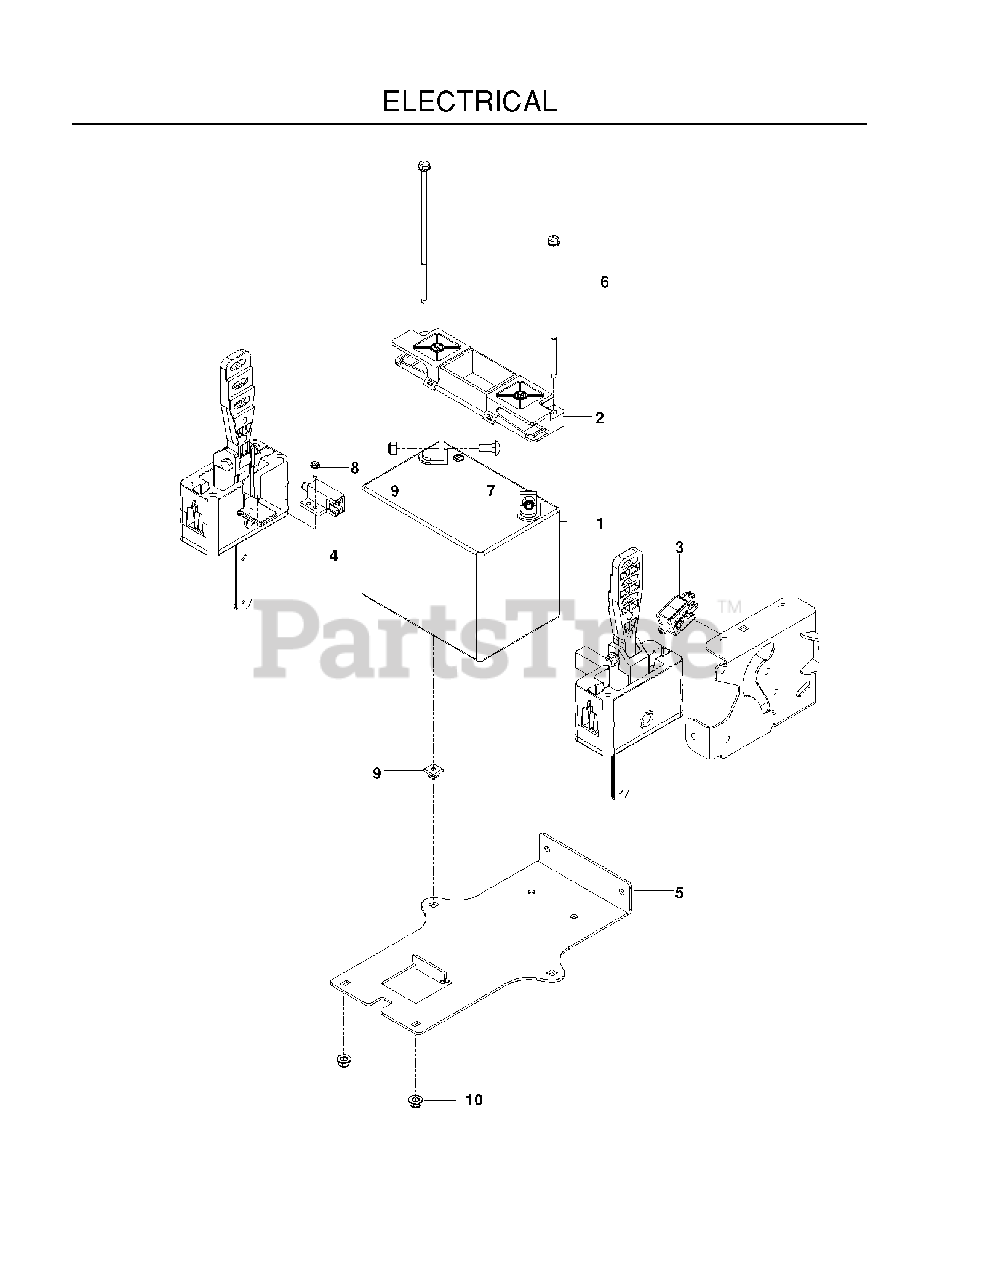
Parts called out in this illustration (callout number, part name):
1	BATTERY, 12 V 330 AMP
2	BATTERY HOLD DOWN
3	SWITCH, BRAKE 3P
4	SWITCH, INTERLOCK
5	PLATE, BATTERY, BLACK
6	BOLT - 1/4-20 X 7.5
7	BOLT 5/16C X 3/4" CARRIAGE
8	SCREW #10 X 1/2 SELF TAPPING
9	PUSH NUT-NYLON
10	5/16-18 NYLOC FLANGE NUT
